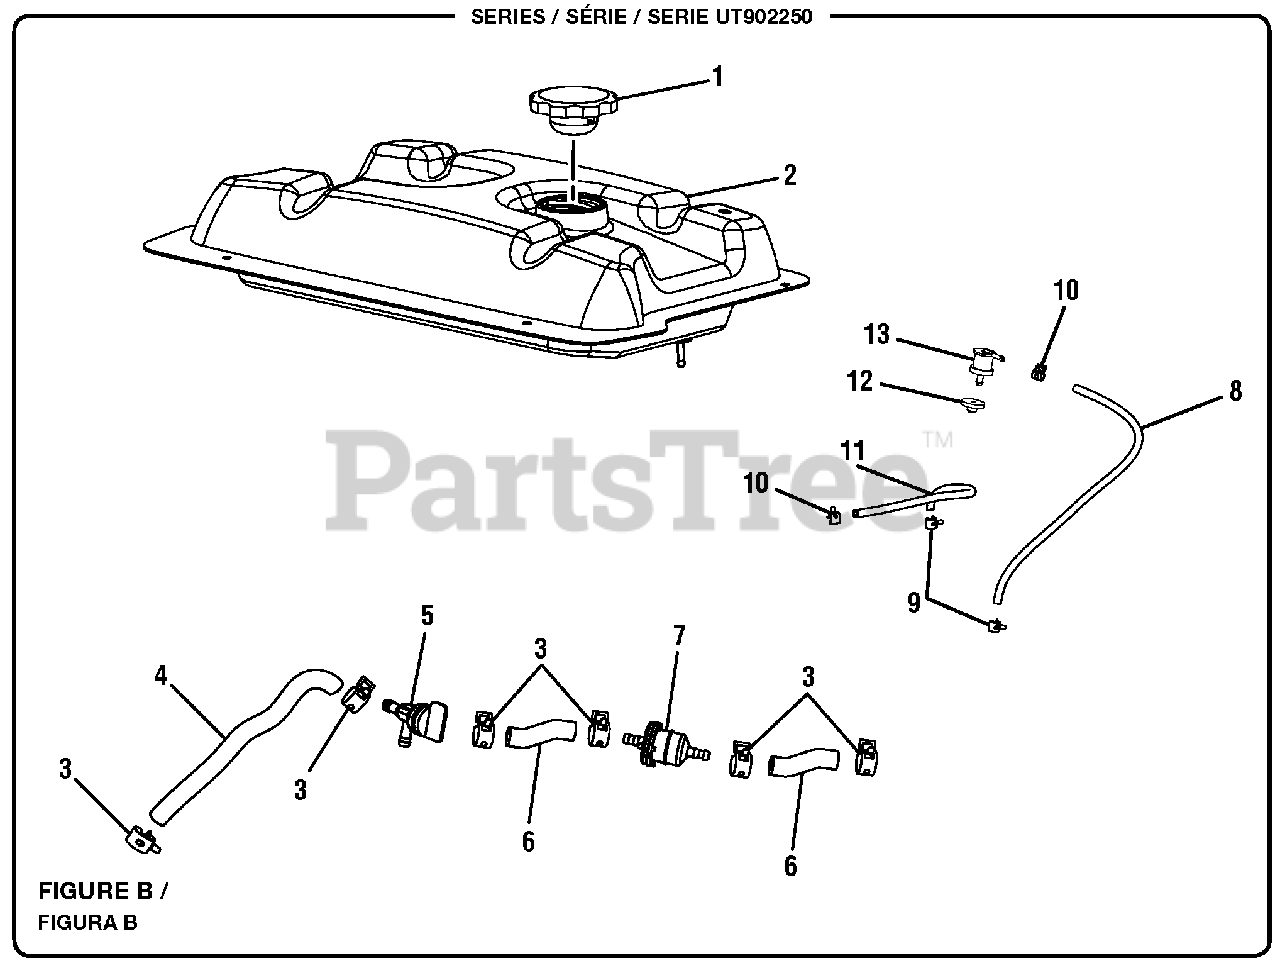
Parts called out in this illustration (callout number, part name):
1	Fuel Tank Cap
2	Fuel Tank
3	Fuel Line Clamp (1/2 in.).
4	Fuel Line Hose (150 mm).
5	Fuel Shut Off Valve
6	Fuel Hose (100 mm)
7	Fuel Line Filter
8	Fuel Line Hose (5 mm, 432 mm)
9	Fuel Line Clamp (3/8 in.).
10	Fuel Line Clamp (5/16 in.)
11	Fuel Line Hose (4 mm, 305 mm)
13	Fuel Check Valve
